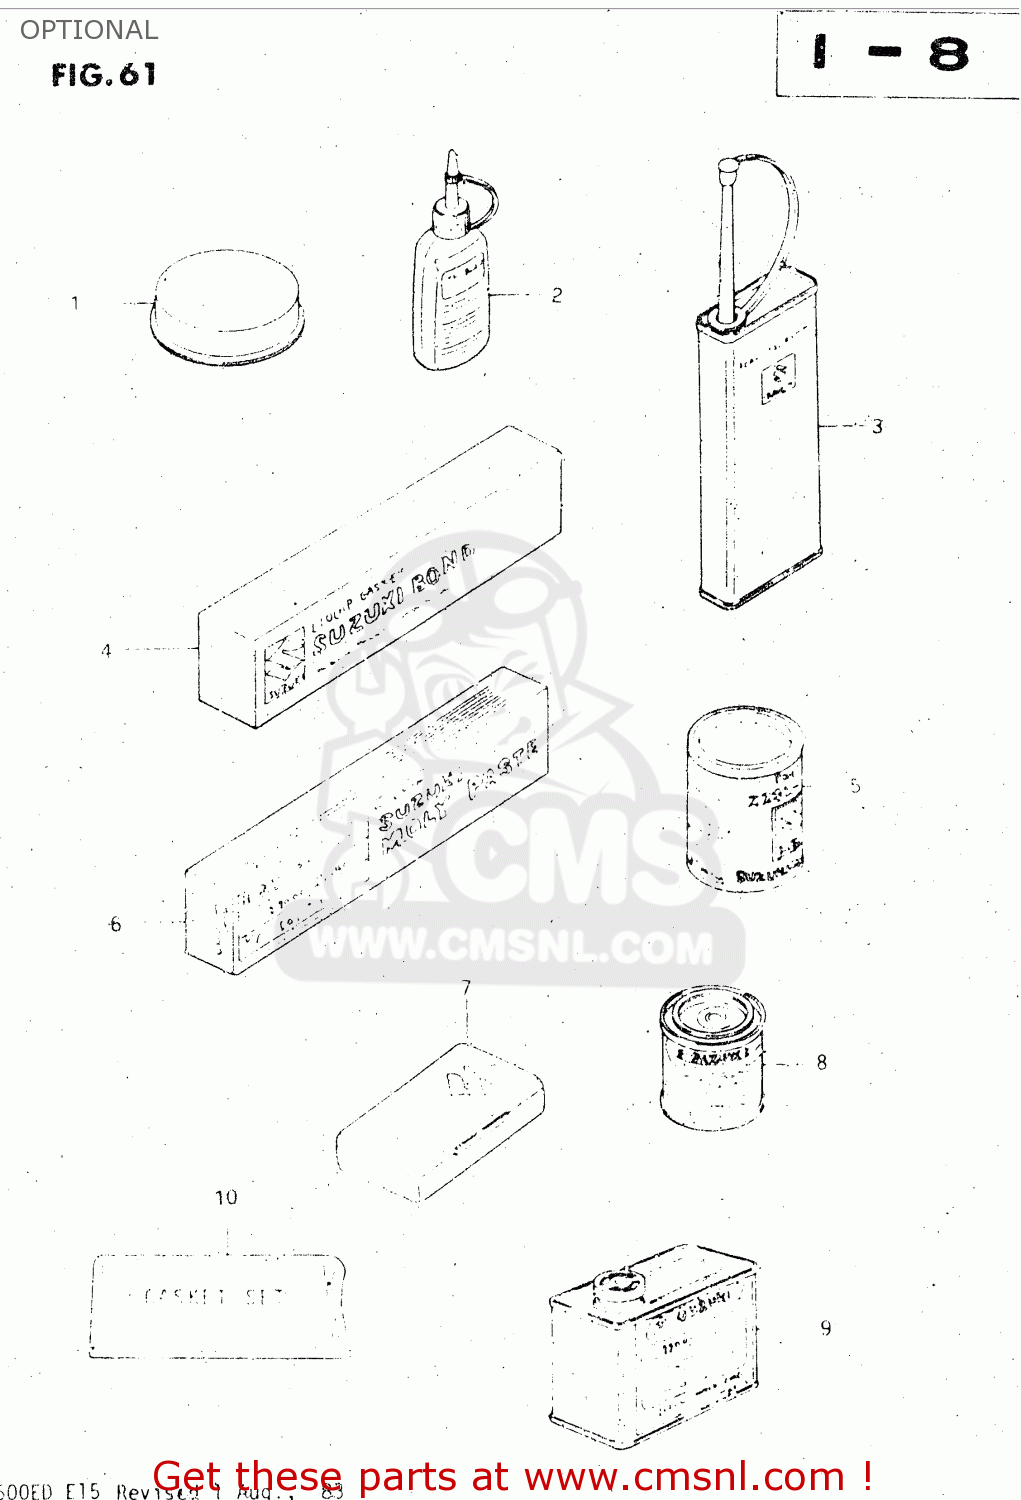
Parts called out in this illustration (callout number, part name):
1	GREASE,PBC FOR BRK PAD 20G
2	THREAD LOCK NO.1342
3	THREAD LOCK NO.1401 CLEAR 200G
4	LIQUID GSKT NO.1215 250G
5	GREASE(C)EP2 LITHIUM 150G
6	SUZUKI MOLY PASTE
7	TUBE REPARING TOOL
8	PAINT,BLACK
9	PAINT (BLACK)
10	GASKET SET
